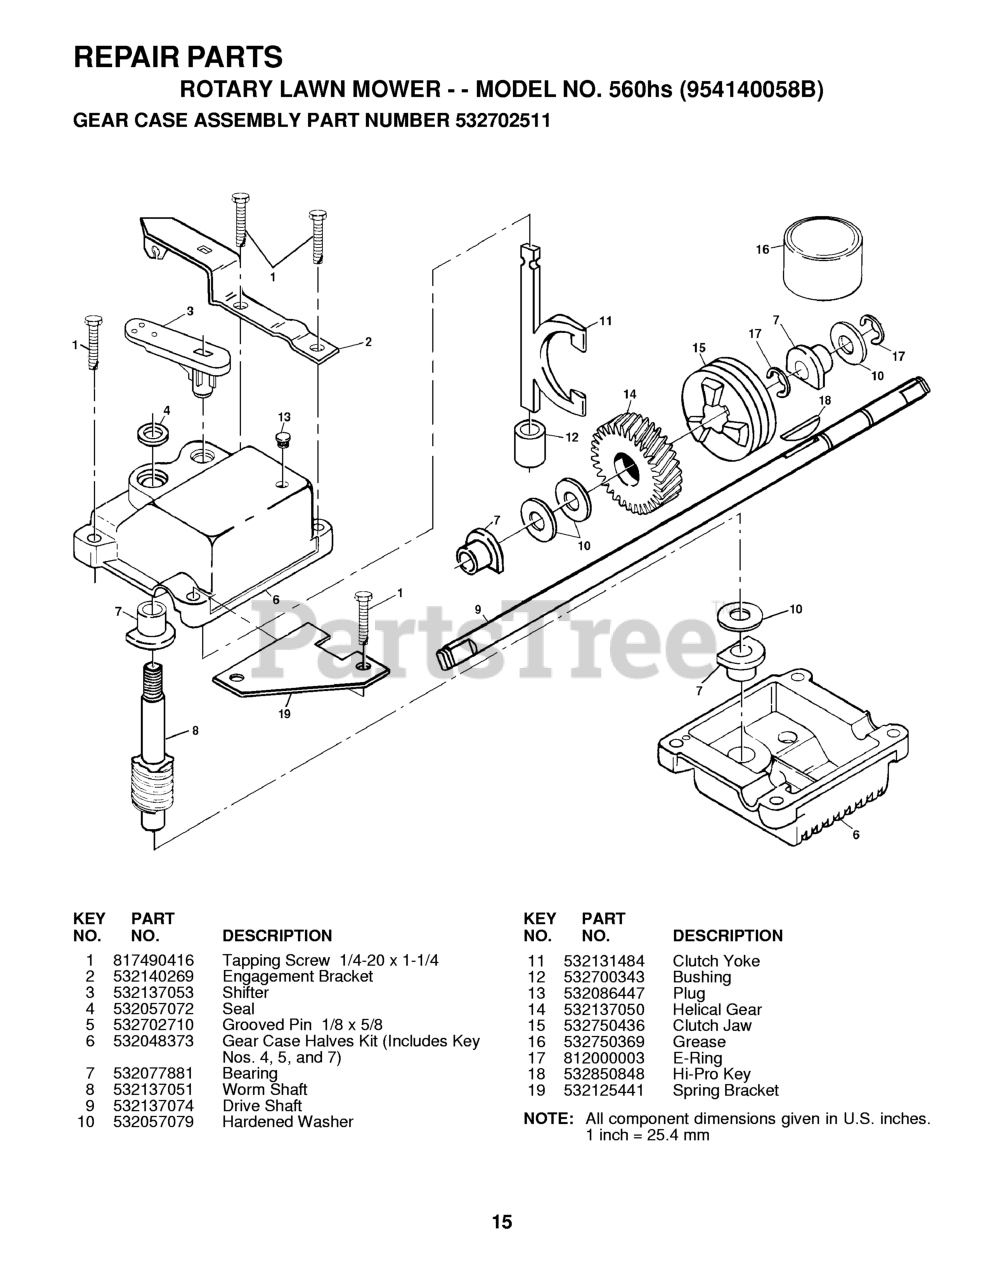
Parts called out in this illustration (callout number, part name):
1	SCREW
2	BRACKET
5	GROOVED PIN
8	WORM SHAFT
9	DRIVE SHAFT, 20-5/8"
10	THRUST WASHER
11	YOKE.VIBRATORY FINISH.
13	PLUG.AUGER.GEAR.BOX.SNOW
14	GEAR.HELICAL
15	CLUTCH JAW
16	GREASE
18	HI PRO KEY
19	BRACKET SPRING
